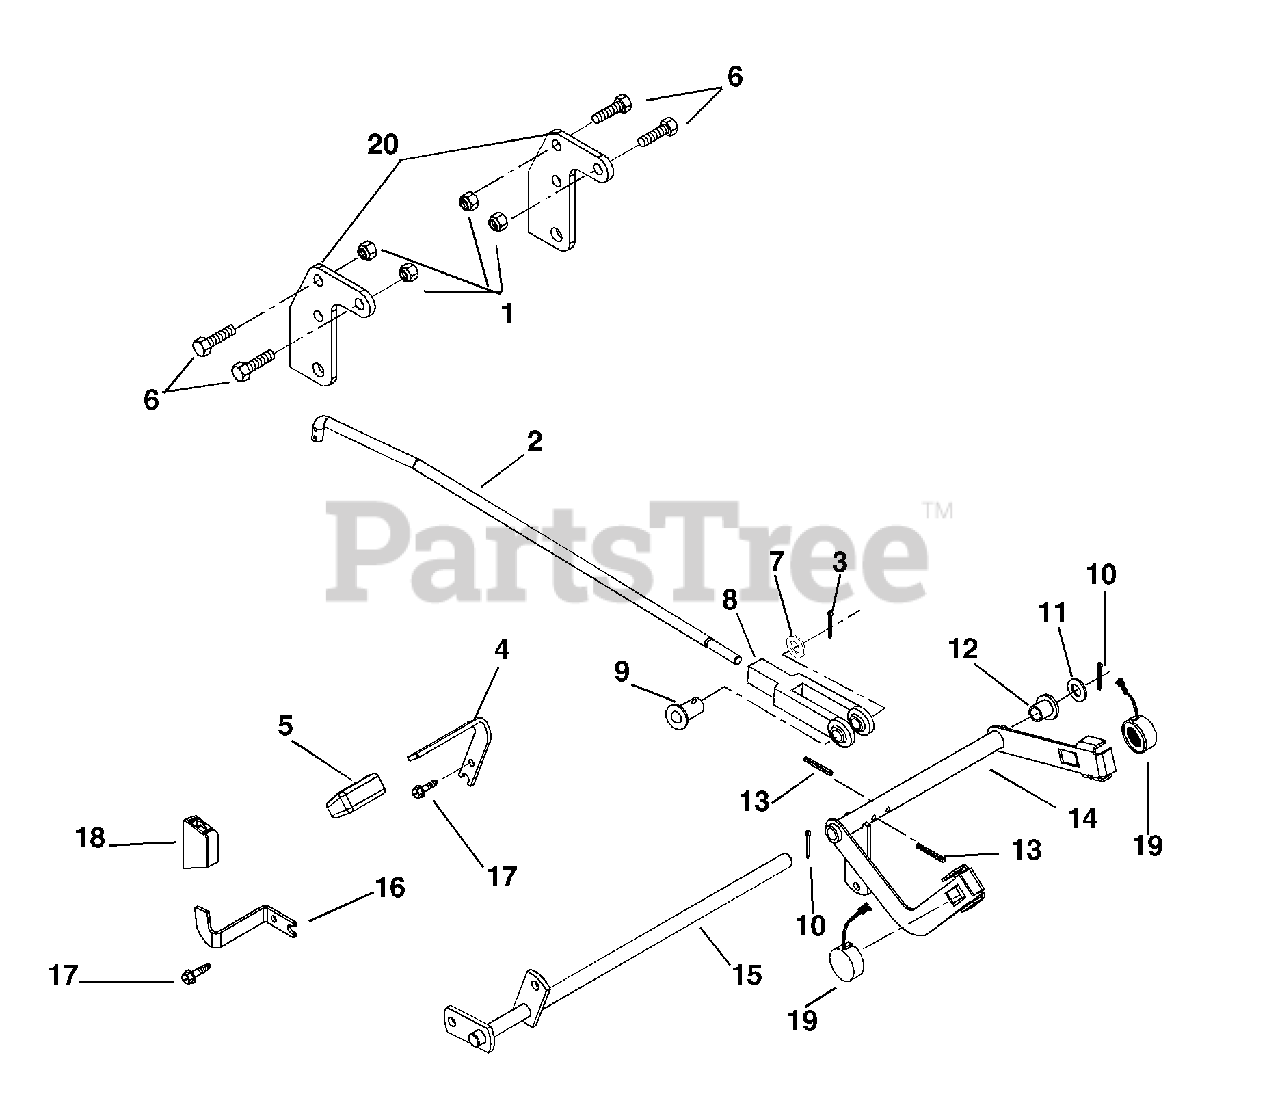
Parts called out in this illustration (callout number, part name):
1	@NUT-LK-CTR .38-16 YWZC
2	ROD, SHIFT
3	@PIN-CTR .09X.75 EXTPRSQCT YWZ
4	PEDAL, FORWARD
5	COVER - PEDAL - FORWARD
6	@BLT-HEX .38-16X.75 GR5 YWZC
7	WSHR-FL-STL .390X.75X.125 YWZC
8	YOKE, .312-24 X 2.25
9	PIN-CLEV .312X.822 HDND PL
10	@PIN-CTR .12X1.00 EXTPRSQCT YZ
11	WSHR-FL-STL .52X.827X.062 YWZC
12	BSHG-FLG .515X.750X.745X1.00NY
13	PIN-GRV .188X1.25 TP A
14	ASSEMBLY, SHIFT ARM
15	SHAFT - PEDAL
16	PEDAL-REVERSE
17	@SCR-TAP .38-16X1.00 HWH TR YZ
18	COVER - PEDAL - REVERSE
20	BRACKET, HANGER
